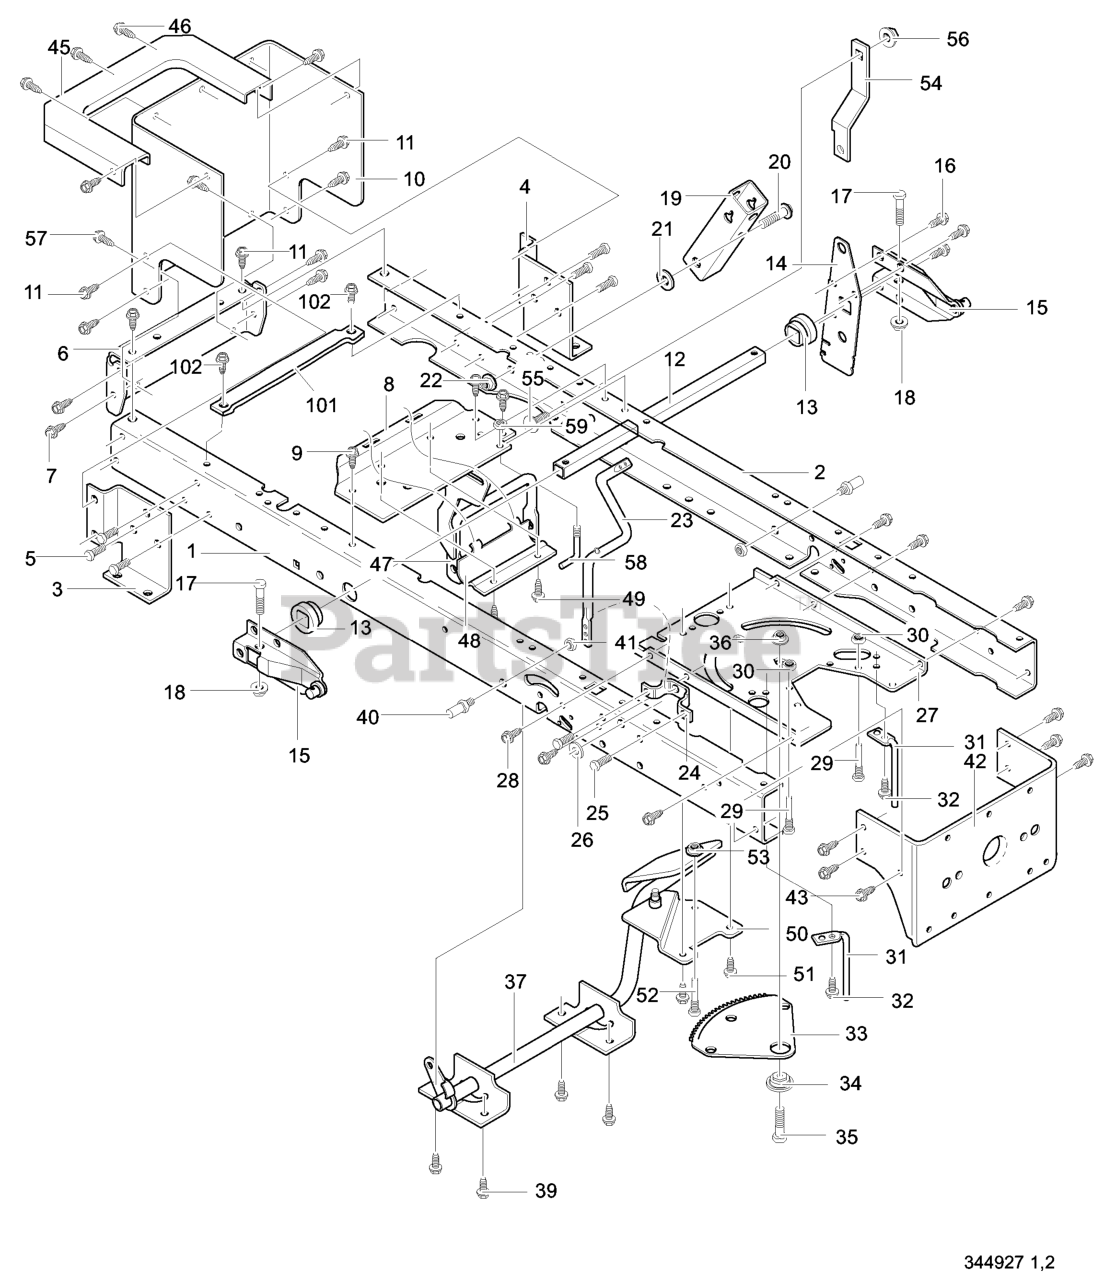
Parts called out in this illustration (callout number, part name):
1	RAIL-FRAME RH SHORT
2	RAIL-FRAME LH SHORT
3	BRACKET-TRANSAXLE RH
4	BRACKET-TRANSAXLE LH
5	SCREW-5/16-18X.75
6	PLATE, HITCH
7	SCREW-5/16-18X.75
8	BRACKET, IDLER
9	SCREW-5/16-18X.75
10	PLATE, REAR
11	SCREW-5/16-18X.75
12	TUBE, LIFTER
13	BUSHING - LIFT TUBE
14	PLATE-LIFT ARM
15	LIFT ARM LEVER
16	SCREW .31X50
17	SCREW, 5/16-24 x 1.25
18	NUT, FLANGELOCK
19	BRACKET, SQ TUBE PIVOT
21	WASHER, FLAT
22	NUT, FLNG CENTERLOCK
23	CRANK, PTO
24	BRACKET, BELL CRANK
25	SCREW-5/16-18X.75
26	WASHER, FLAT
27	PLATE, STEERING
28	SCREW-5/16-18X.75
29	ZINC SCREW GUIDE 5/16-18
30	NUT.32-18 FLANGELOCK
31	GUIDE, BELT
32	BOLT
33	GEAR, SECTOR
34	BEARING, SECTOR GEAR
35	CAPSCREW, Hex Head, 5/16-18 x 1
36	NUT, 5/16
37	PEDAL
39	SCREW-5/16-18X.75
40	PIN,THREADED SHOULDER
41	NUT, 3/8-16
42	BRACKET, HANGER REAR
43	SCREW-5/16-18X.75
45	TOP, REAR PLATE
46	SCREW - THREAD FORM
47	YOKE ASSY-TRUNNION
48	CLAMP, TRUNNION PIVOT
49	SCREW-5/16-18X.75
50	IDLER INTERMEDIATE
51	SCREW, 5/16-18 x 0.50
52	SCREW GUIDE 5/16-18
53	NUT, FLANGELOCK
54	BRACKET, Torque Strap, LH
55	BOLT, CARRIAGE 31-18X0.62
56	NUT, CENTERLOCK
57	BOLT-3/8 X 1.25
58	SCREW - GUIDE
59	NUT, FLANGELOCK
101	BRKT, BATTERY SUPPORT
102	SCREW-5/16-18X.75
